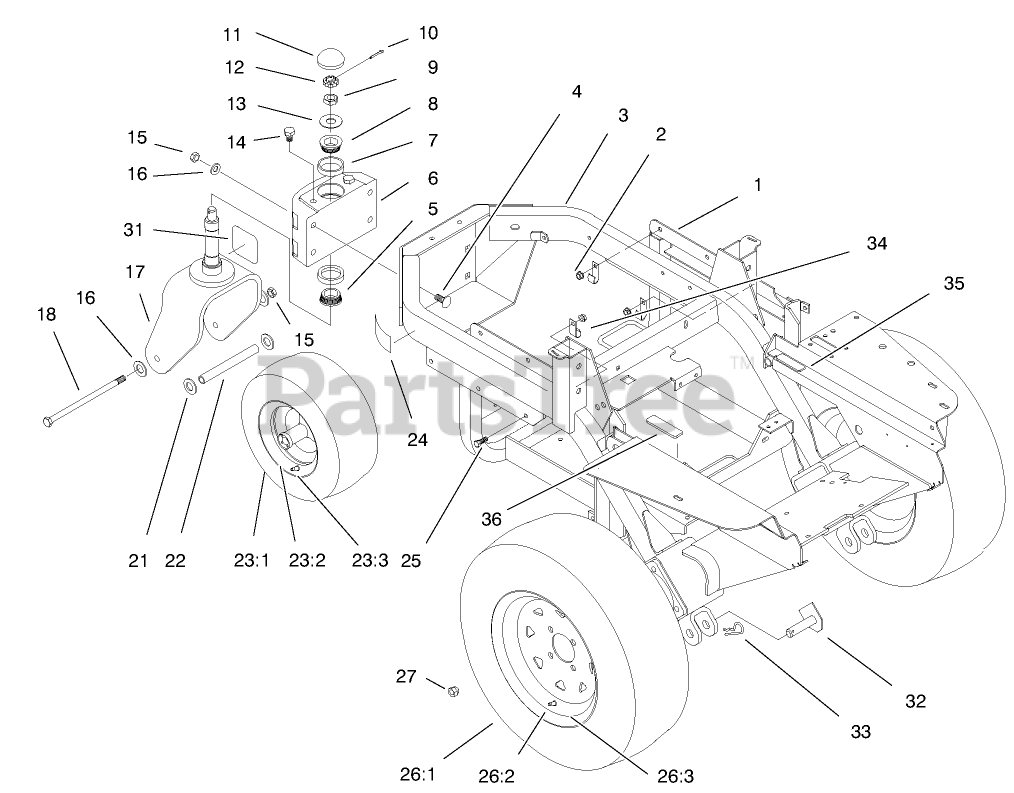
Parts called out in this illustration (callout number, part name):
1	ENGINE SUPPORT ASM
2	NUT-LOCK, NI
3	FRAME ASM W/ DECALS
4	SCREW-CARR
5	BEARING-CONE
6	HOUSING - SPINDLE
7	CUP-BEARING, ROLLER
8	BEARING-ROLLER, CONE
9	NUT-JAM
10	PIN-COTTER
11	DUSTCAP
12	NUT-LOCK, RETAINER
13	WASHER-FLAT
14	SCREW-HH
15	NUT-LOCK, NI
16	WASHER-FLAT
17	CASTER FORK ASM
18	SCREW-HH
19	DECAL - PATENT NUMBERS, OFZ
21	WASHER-FLAT
22	TUBE-SPACER, CASTOR
23:2	WHEEL ASM
23:3	STEM-VALVE
24	DECAL-HOT SURFACE
25	SCREW-HH
26:1	Tire
26:2	STEM-VALVE
26:3	WHEEL
27	NUT-LUG
31	DECAL - Z325
32	PIVOT PIN ASM
33	PIN-HAIR
34	CLIP
35	PAD-RUBBER
36	DECAL-WARNING
